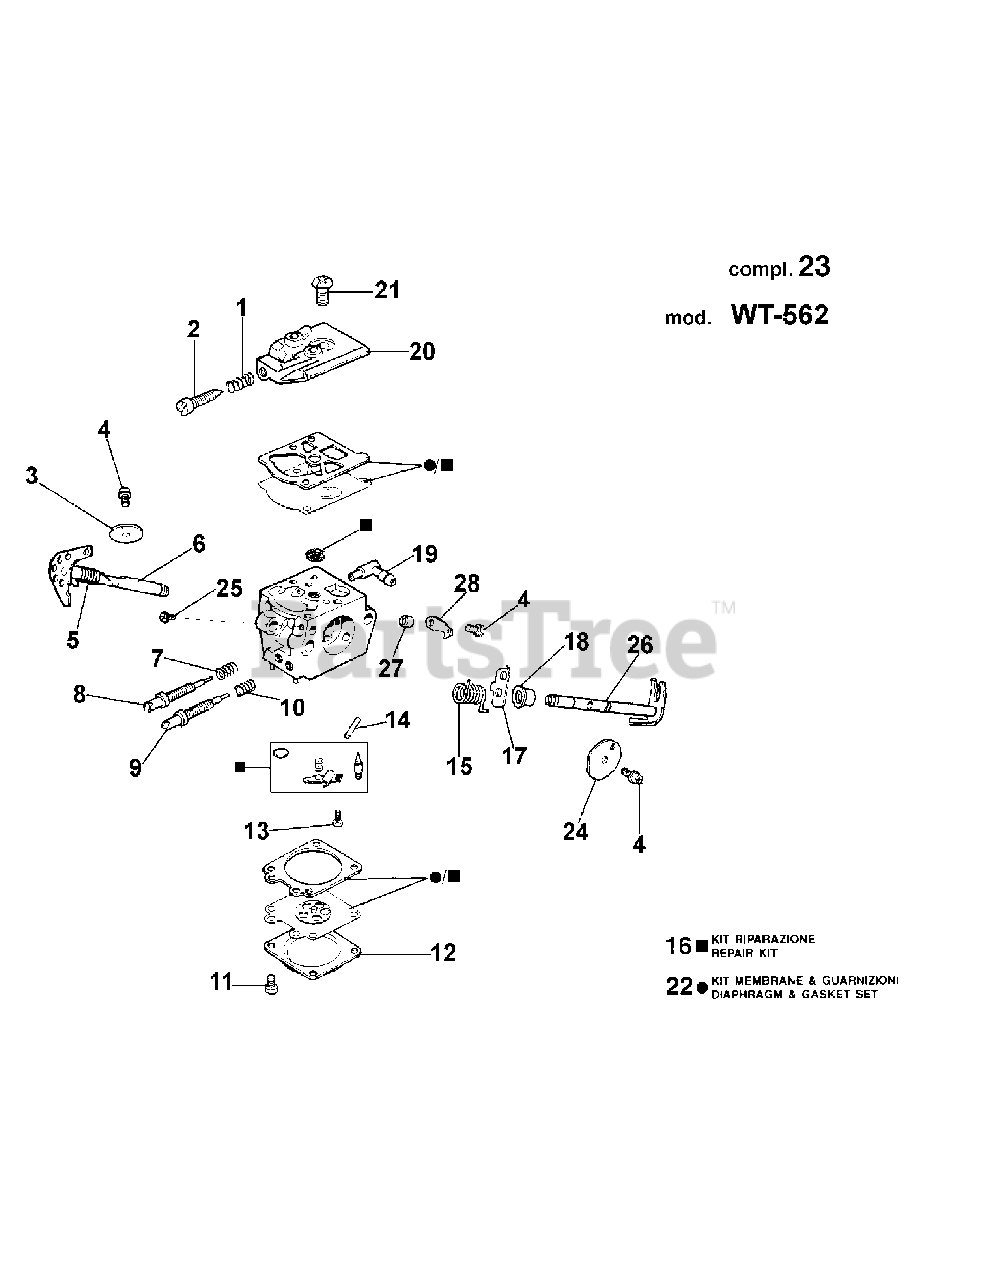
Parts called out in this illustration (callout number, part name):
3	CHOKE SHUTER
6	SHUTER SHAFT
19	ELBOW CONNEC..
22	DIAPH/GASKET
23	CARBUR.
24	CHOKE SHUTER
26	STARTER SHAFT
